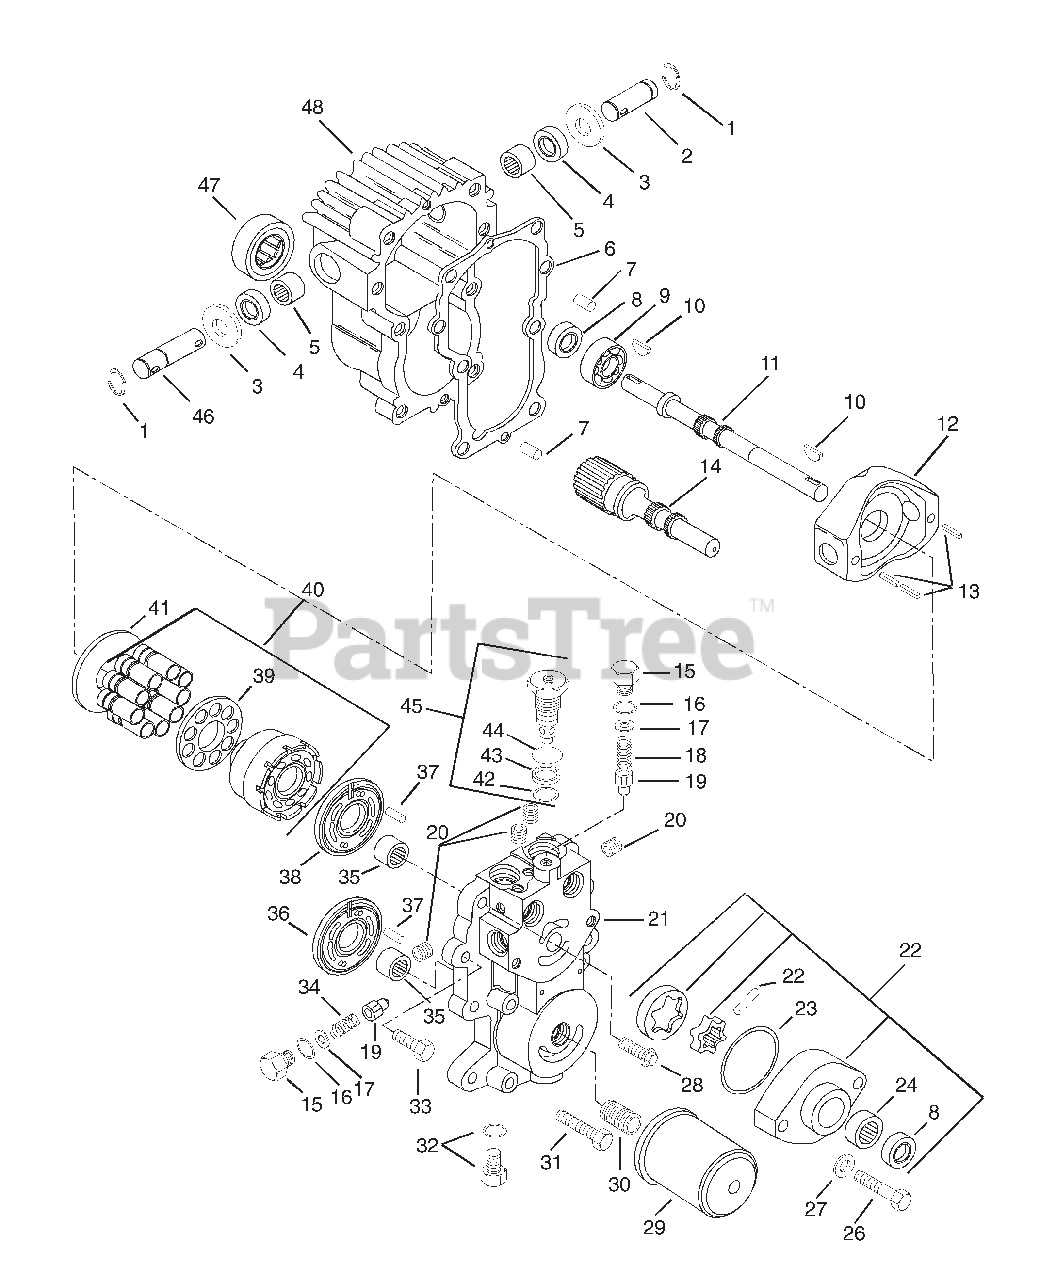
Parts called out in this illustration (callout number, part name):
1	RG-RTNG-EXT .688X.042
2	TRUNNION SHAFT
3	WSHR-FL-STL .699X1.375X.059
4	SEAL .625X1.187X.187
5	BRG-NEEDLE .688X.876X.63
7	DOWEL PIN
8	SEAL .625X1.128X.250
9	BRG-BALL 1.0X2.0X.50
10	KEY-WDRF .188X.75X.313 SAE 9
11	PUMP SHAFT
12	SWASHPLATE VARIABLE
13	PIN-ROLL .188X.63
14	MOTOR SHAFT
15	PLUG-HEX HEAD
16	O-RING .414X.562X.072
17	SHIM PACKAGE
18	SG-COMP ??X??X?? SUNSTRAND
19	RELIEF VALVE CONE
20	PIPE PLUG
21	CENTER SECTION
23	O-RING 2.364X2.504X.072
24	BRG-NEEDLE .625X.875X.50
25	CHARGE PUMP ASSEMBLY
26	BLT-HEX .44-14X2.00 GR5
27	WSHR-FL-STL .469X.719X.108
28	SCR-12PNT .38-16X1.25 GR5
29	OIL FILTER
31	BLT-HEX .38-16X2.00 PL GR5
32	THREADED PLUG
33	BLT-HEX .38-16X1.50 PL GR5
34	SG-COMP ??X??X?? SUNSTRAND
35	BRG-NEEDLE 17MMX.938X.62
36	MOTOR VALVE PLATE
37	DOWEL PIN
38	VALVE PLATE
39	SLIPPER RETAINER
40	CYLINDER BLOCK KIT
41	THRUST PLATE
42	O-RING .614X.750X.070
43	O-RING .614X.750X.046
44	O-RING .770X.968X.097
45	CHECK VALVE ASSEMBLY
46	TRUNNION SHAFT
47	BRG-ROLLER 1.27X2.05X15MM
48	HOUSING W/SEALS AND BEARINGS
